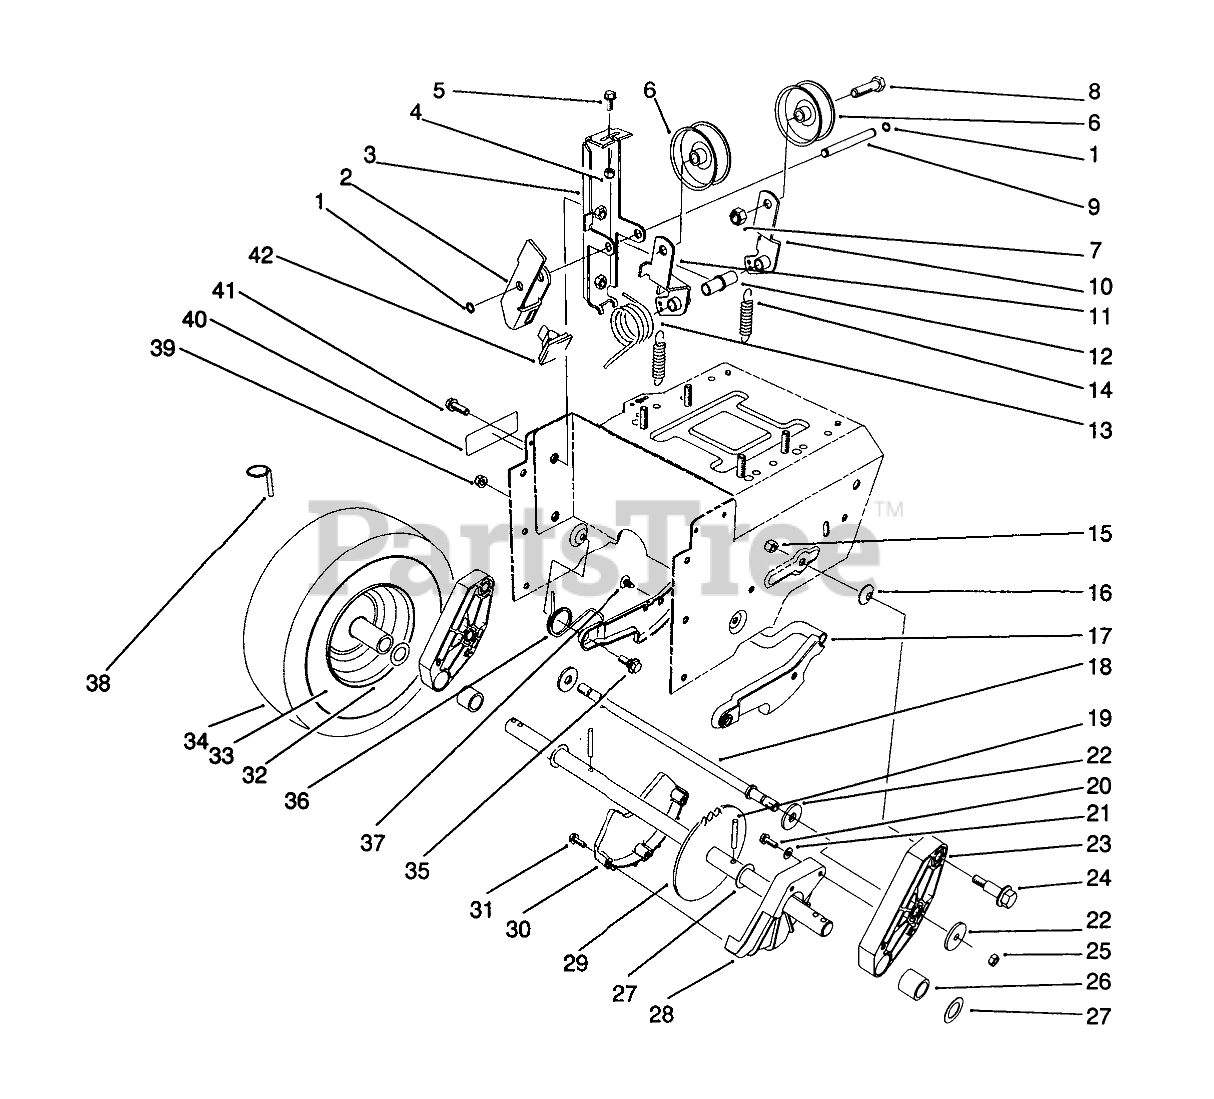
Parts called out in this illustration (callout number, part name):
1	RING-RETAINING
2	ARM-BRAKE
3	IDLER ARM BRACKET ASM
4	NUT-LOCK, NI
5	SCREW-HHF
6	PULLEY-IDLER
7	NUT-LOCK, NI
8	SCREW-HH
9	PIN-IDLER
10	ARM-IDLER, TRACTION
11	ARM-IDLER, IMPELLER
12	BUSHING-IDLER
13	TORSION SPRING
14	SPRING-EXTENSION
15	NUT-LOCK, NI
16	WASHER-SPRING
17	Latch-Arm
18	ROD-LATCH
19	PIN-ROLL, SLOTTED
20	SCREW-HWH
21	WASHER-FLAT
22	WASHER-SUPPORT
23	Pivot Arm Assembly (Incl. Ref. #26)
24	BOLT-SHOULDER
25	NUT-LOCK, NI
26	BUSHING-AXLE
27	WASHER-THRUST
28	GUARD-CHAIN, LH
30	GUARD-CHAIN, RH
31	Screw
32	RIM-WHEEL
33	INNER TUBE
35	SCREW-SHOULDER
36	SPRING-LATCH, TORSION
37	FASTENER-PANEL
38	PIN-LYNCH
39	NUT-LOCK, NI
40	DECAL-WARNING
41	SCREW-HHF
42	PAD-BRAKE
